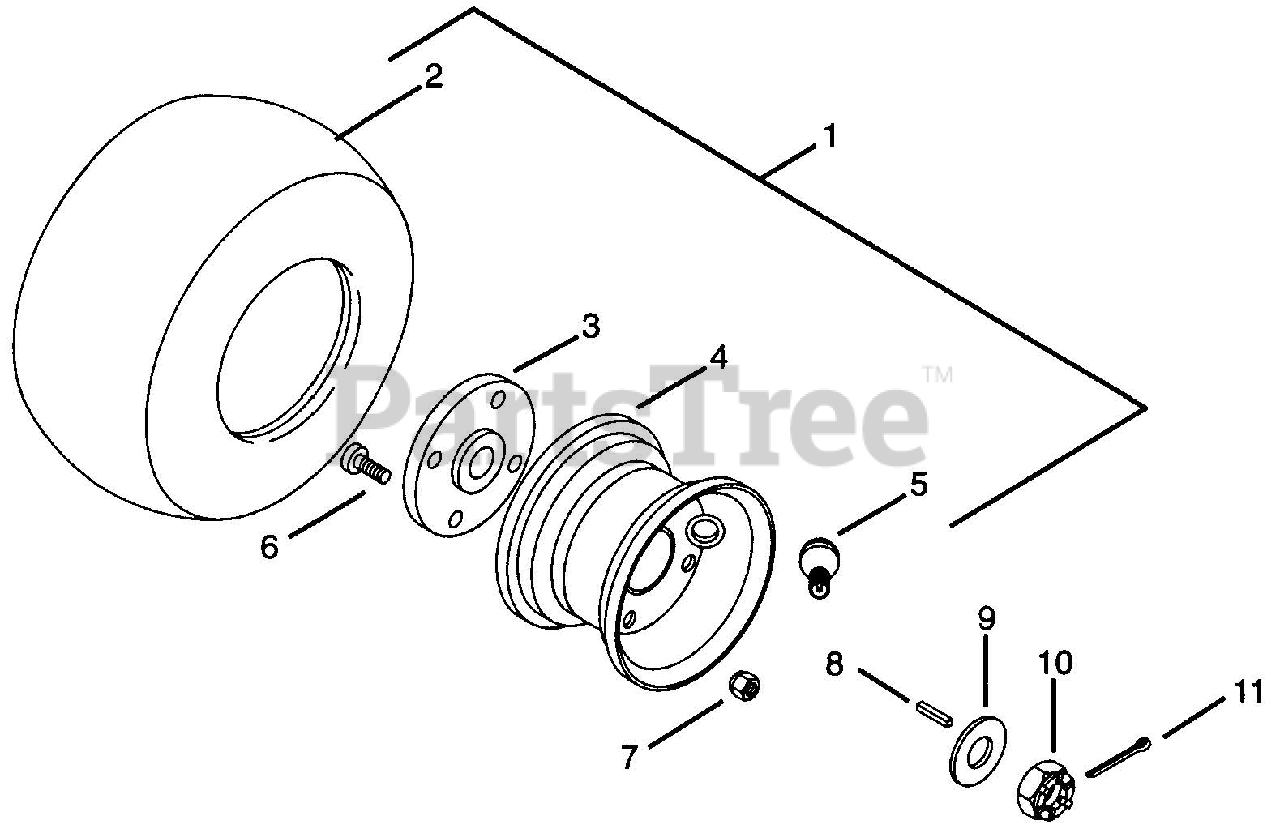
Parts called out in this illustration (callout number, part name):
1	Tire/Wheel Assembly 16 x 6.50-8
2	Tire 16 x 6.50-8
3	Assembly - Hub
4	Assembly - Rim
5	Valve Stem Assembly
6	Bolt .50-20 x 1.25
7	Nut-Hex .50-20
8	Key-Square 3/16 x .750
9	Washer-Flat-Steel .781 x 1.5000 x .060
10	Nut-Hex 3/4-28
11	Pin-Cotter .09 x 1.0
